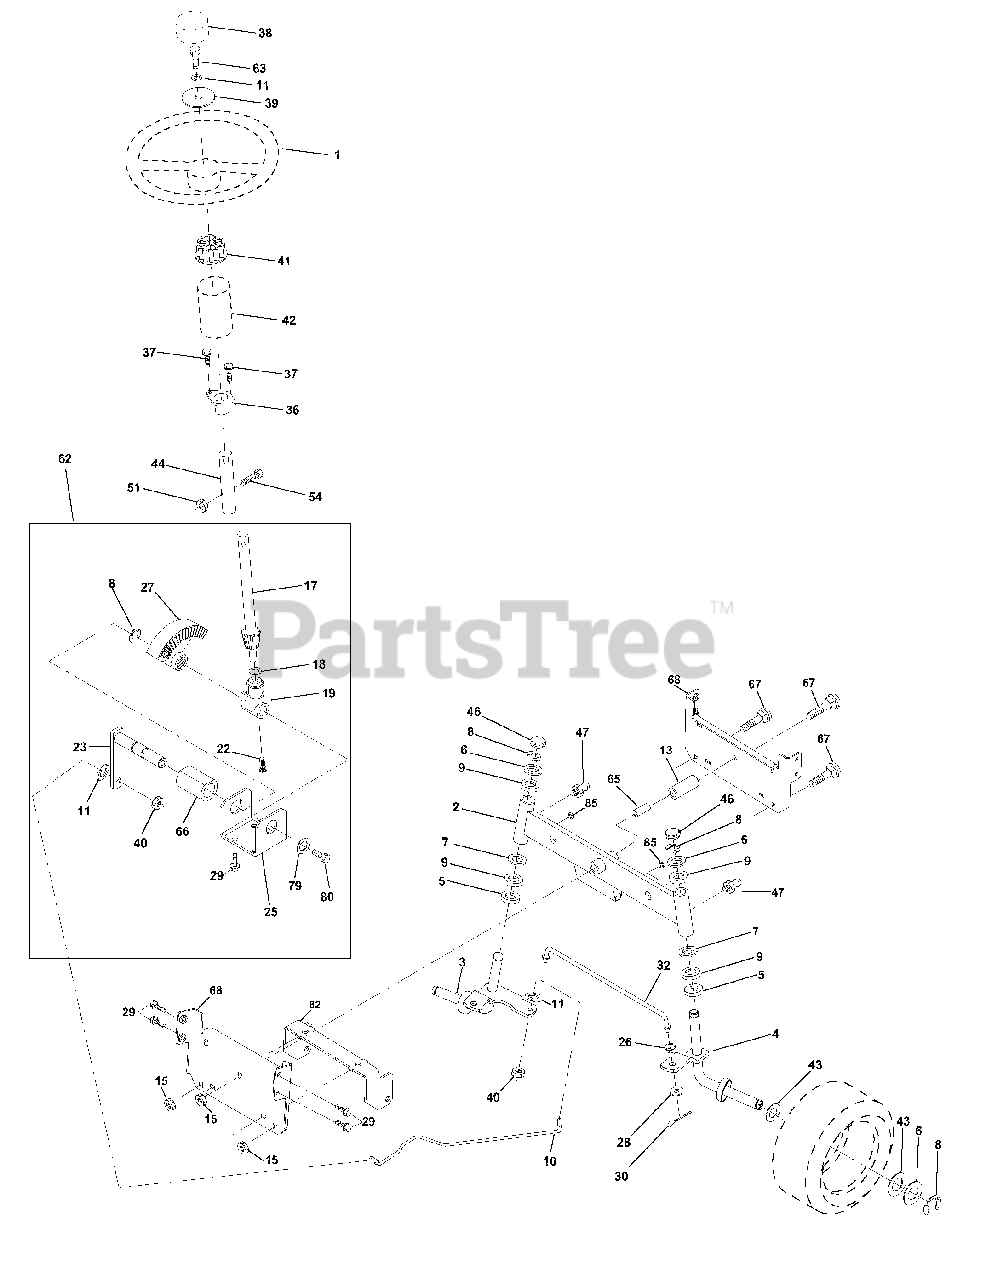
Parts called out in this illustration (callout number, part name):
1	Wheel Steering Ayp/P/L Blk
2	Axle Asm
3	Spindle Asm LH
4	Spindle Asm RH
5	Bearing Race Thrust Harden
6	Washer 25/32 X 1-5/8 X 16 Ga
7	Washer 27/32 X 1-1/4 X 16 Ga
8	Ring Klip #t5304-75
9	Bearing Col Strg Blk
10	Link Drag
11	Washer Lock Hvy Hlcl Spr 3/8
13	Spacer earing Axle Front
15	Hexflange Lock
17	Shaft Asm Strg
18	Washer Thrust 515x 750x 033
19	Support Shaft
22	Screw Hex Wsh Hd Torx
23	Shaft Asm Pittman
25	Bracket Steering
26	Bushing Link Drag Blk LR
27	Gear Sector
28	Washer 13/32 X 7/8 X 16 Ga
29	Screw 3/8-16 x 3/4
30	Pin Cotter 1/8 X 3/4 Cad
32	Rod Tie Wire Form 19 75 Mech
36	Bushing Strg 5/8 Id Dash
37	Screw
38	Cap Wheel Steer Ayp
40	Nut Lock Center 3/8-24un
41	Adaptor Wheel Strg
42	Boot Dash Mtl Steering Blk
43	Washer 25/32 X 1 1/4 X 16 Ga
44	Extension Steering
46	Cap Spindle Fr Top Blk
47	Fitting Grease
51	Nut Lock Hex W/Ins 5/16-18
54	Bolt Fin Hex 3/8-16unc x 1-1/4
62	Kit Steering Assembly Service
63	Bolt Fin Hex 3/8-16unc x 1 Gr.5
65	Spacer Brace Axle
66	Bearing Arm Pittman
67	Bolt Fin Hex 5/8-11 unc x 2-3/4
68	Brace Axle
79	Washer 13/32 x 1 1/4 x 12 Ga.
80	Bolt Hex 3/8-16 x 3/4
82	Bracket Susp Chassis Front
85	Fastener Christmas Tree
